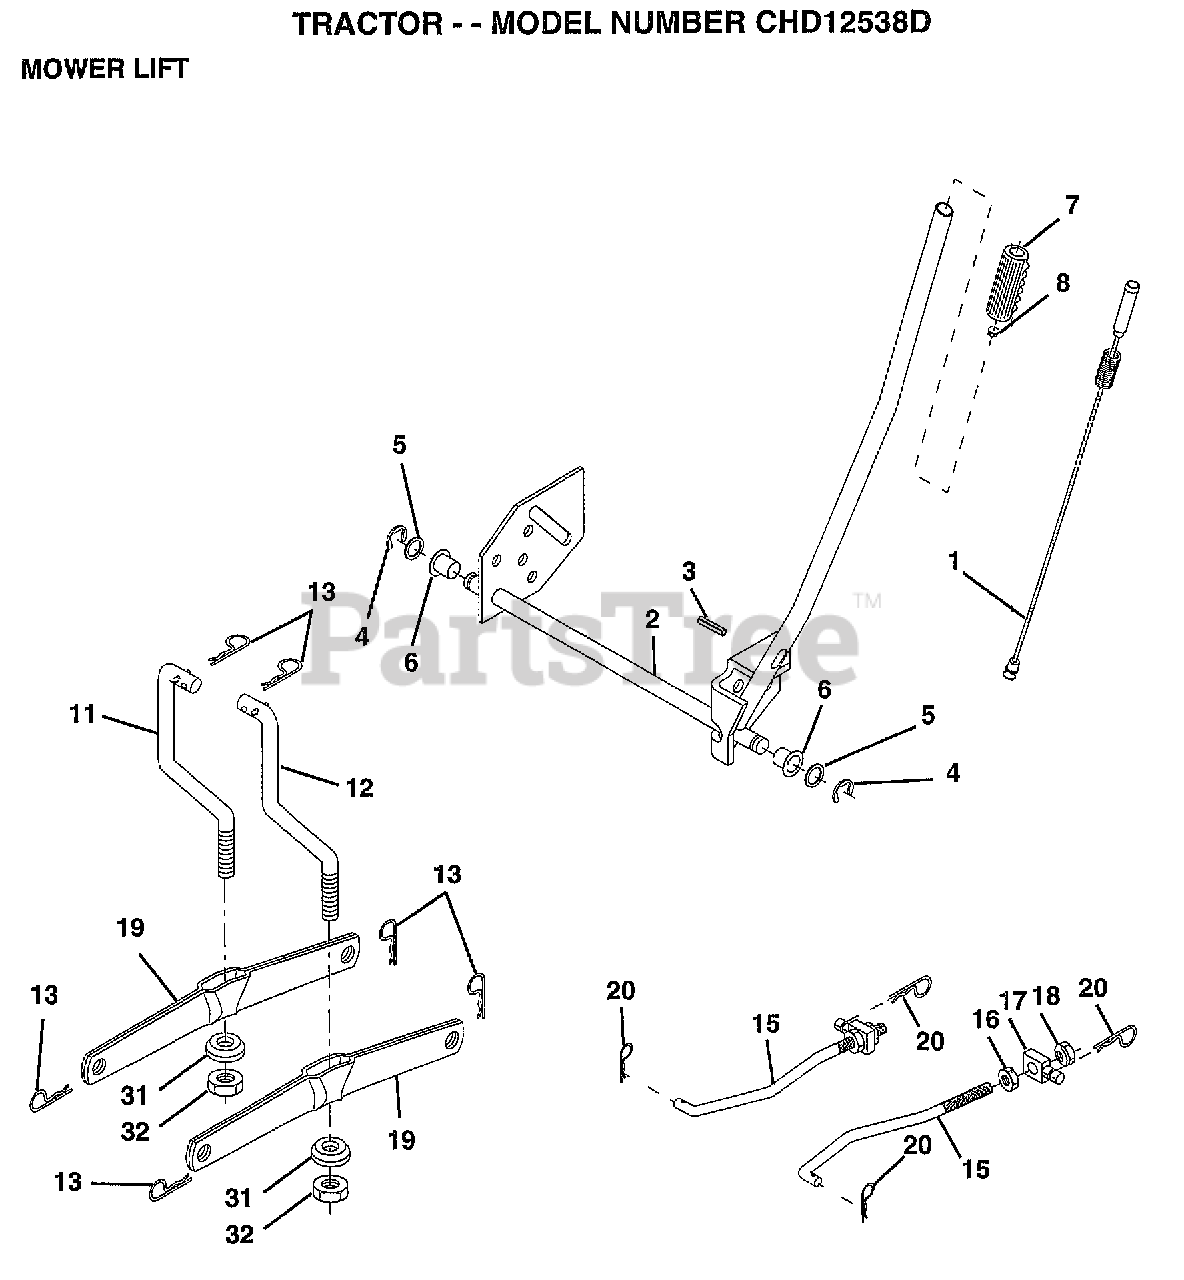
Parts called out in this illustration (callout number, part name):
1	MANUAL.O.3489B59
2	"SHAFT ASM LIFT,RH"
3	PIN-GROOVE LT
5	WASHER
6	NYLON BEARING
7	GRIP
15	LINK.FRONT
16	NUT
17	TRUNION
18	NUT.LK.W/WSH.1/2.
19	ARM SUSP REAR
20	RETAINER SPRING
31	BEARING PVT LH
32	NUT.CROWNLOCK.3/8
